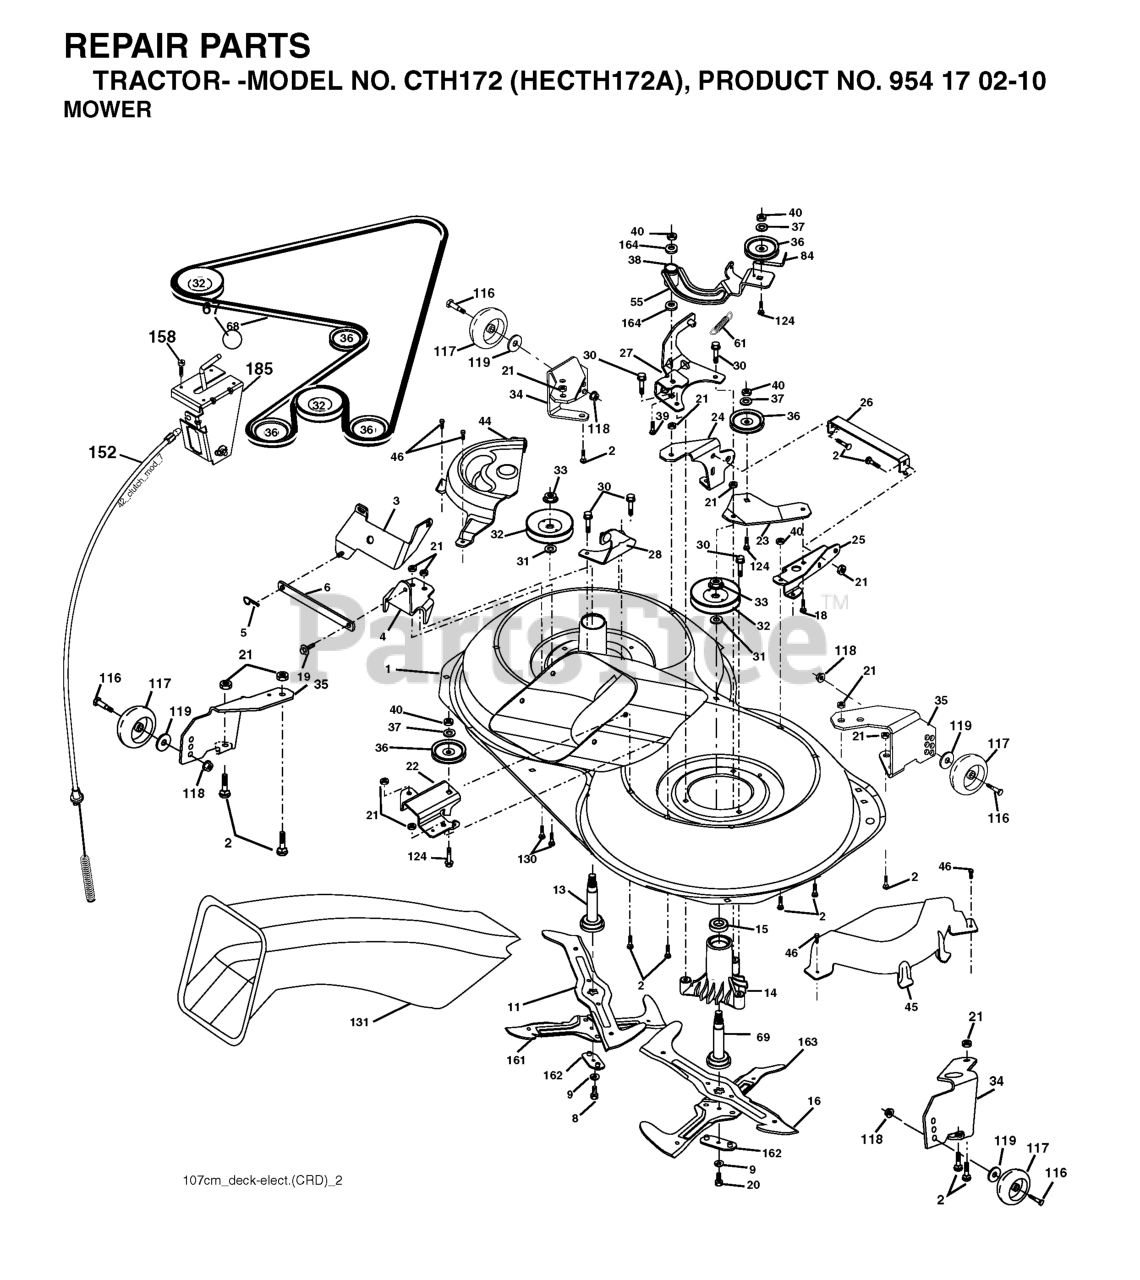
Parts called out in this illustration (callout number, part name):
1	Housing Asm. Mower 107 CRD
2	RP BOLT 5/16-18 X3/4 ZN/YEL GR
5	RETAINER-SPRNG RB
6	BAR.SWAY.92.CRD
8	BOLT.3/8-24X1.25 GR8
9	LOCKWASHER
11	BLADE.3N1.LH.CRD
13	SHAFT ASM VENT
14	HOUSING.MANDREL.VENTED (MACHD)
16	BLADE.3N1.RH.CRD
18	BOLT D
19	BOLT SHD 5/16-18
20	BOLT.3/8-24X1.25GR8. LHTHRD
21	LOCKNUT
22	BRACKET.IDLER.RR.107.CRD
25	BRACKET.SUSPENSION.RF.107.CRD
26	BRACE.SUPT.SUSP.FRT.CRD
28	BRACKET
30	SCREW, WASHER HEAD
31	WASHER.SPACER.MANDREL
33	NUT, FLG TOPLOCK 9/16"
36	PULLEY.IDLER.4.25
37	WASHER
45	COVER.MANDREL.RH.CRD
46	SCREW.1/4-20X5/8
55	ARM.IDLER.107.CRD
68	HEX-BELT 107 MOWER
69	SHAFT.ASM.W/LWR.BRG.RH.THREAD
84	KEEPER, BELT IDLER
116	SHOULDER BOLT
117	WHEEL GAGE DONUT
118	LOCKNUT
119	WASHER.5/16.FLAT.STE.STD.
124	BOLT.3/8-16X1.50
130	BOLT.CARR.SQNK.5/16-18UNC.X3/4
131	CHUTE BAGGER
158	SCREW
163	BLADE.CROSS.RH.CRD.107
164	BRNG T
185	HEAD ASM. CABLE CLUTCH
